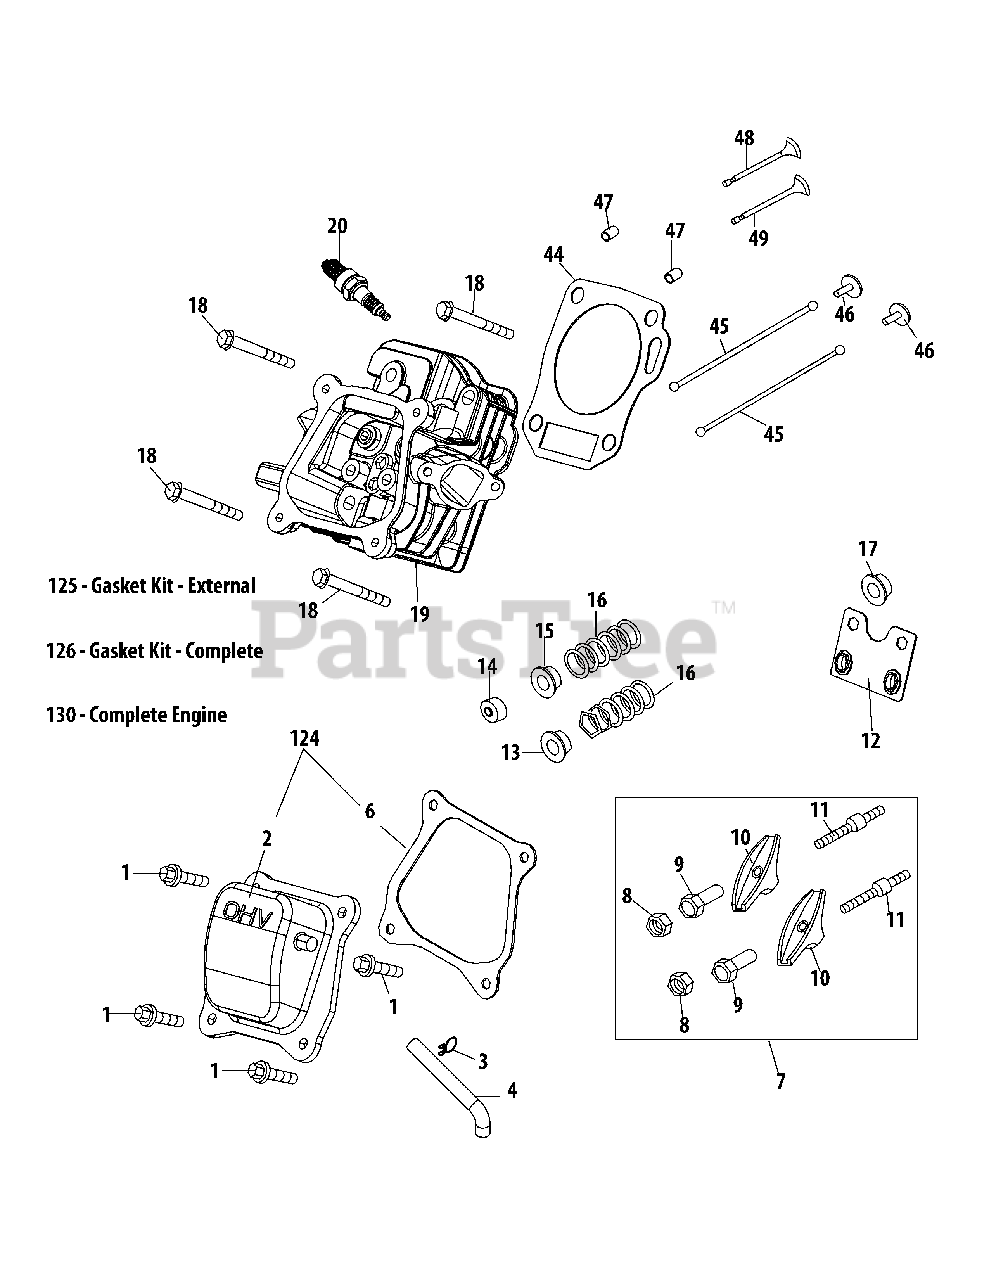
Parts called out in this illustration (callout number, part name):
1	Bolt M6×16
2	Valve Cover
3	Breather Hose Clamp
4	Exhaust Piping
6	Valve Cover Gasket
7	Rocker Arm Assembly
8	Nut, Pivot Locking
9	Adjusting Nut ,Valve
10	Rocker Arm
11	Bolt, Pivot
12	Push Rod Guide
13	Retainer, Intake Valve Spring
14	Adjuster, Exhust Valve
15	Retainer, Exhust Valve Spring
16	Valve Spring
17	Intake Valve Seal
18	Bolt M8×55
19	Cylinder Head Service Kit
19	Cylinder Head Assembly
20	Spark Plug/F6Rtc
44	Gasket, Cylinder Head
45	Push Rod Kit
47	Dowel Pin 10×16
124	Valve Cover Kit
125	Gasket Kit - External
126	Gasket Kit - Complete
130	Complete Engine
